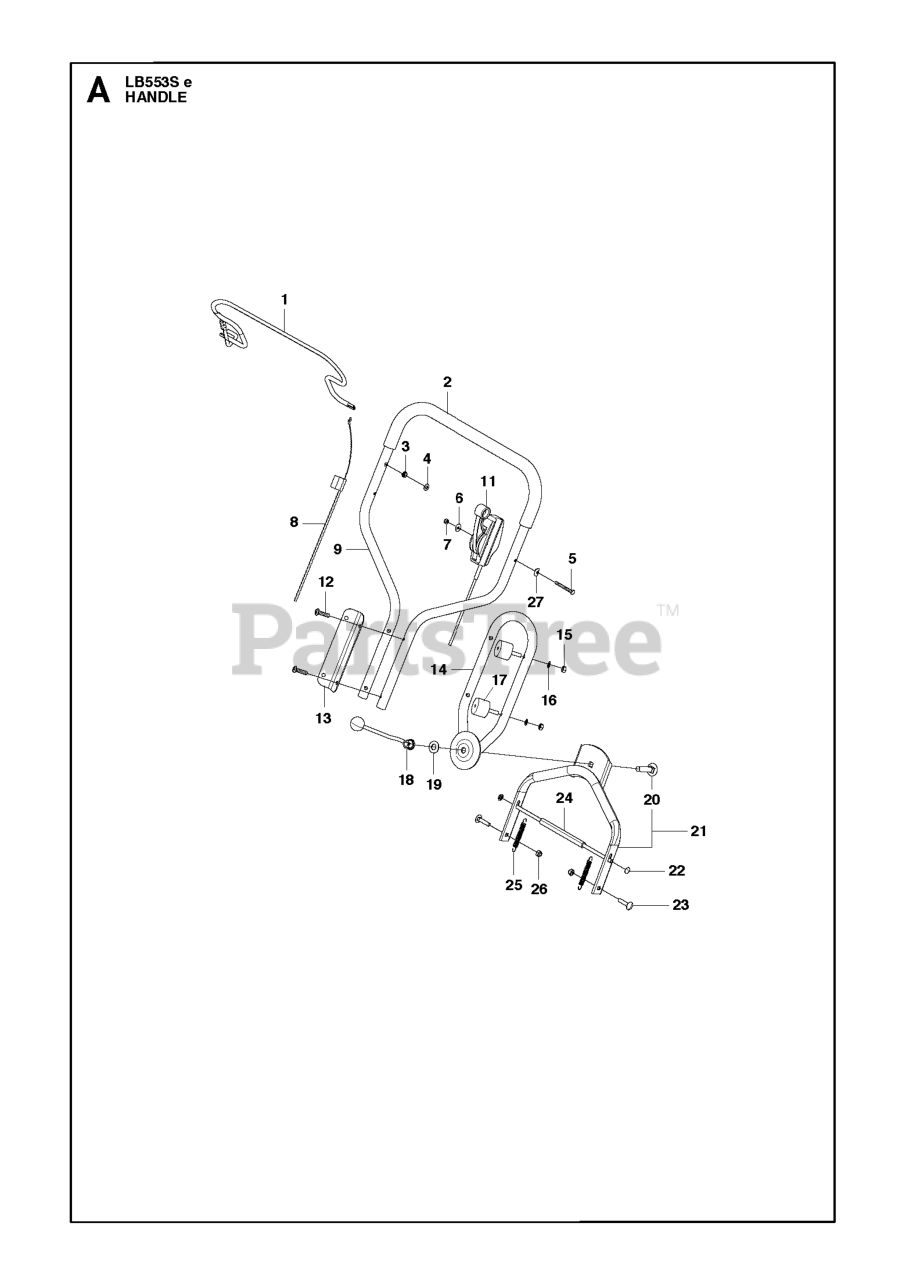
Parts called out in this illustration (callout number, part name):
5	SCREW M6X55
7	NUT FLANGE - M6
15	NUT
22	WASHER STARLOCK WITH CAP
26	LOCKNUT M8
